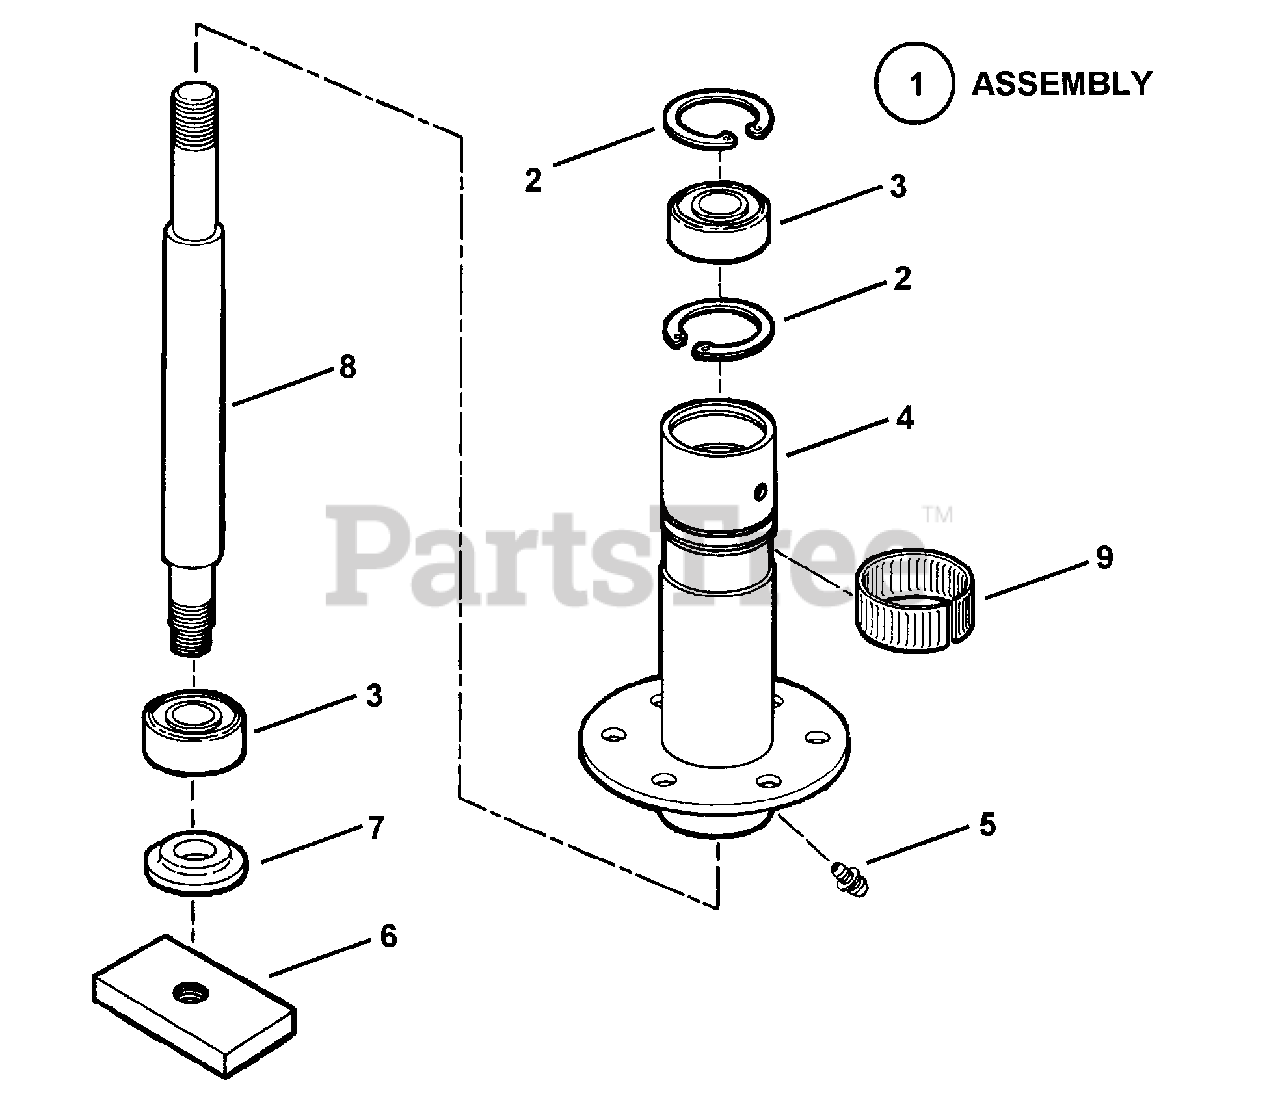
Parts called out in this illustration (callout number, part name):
1	ASSEMBLY, Spindle Housing
2	RING, 1.75" Internal Retaining
3	BEARING, Spindle
4	HOUSING, Spindle (7.5" Tall)
5	FITTING, Lube (Press fit for .187 hole-no ball)
6	HOLDER, Blade
7	WASHER, Spindle
8	SPINDLE (9.5" Length)
9	RING, Tolerance
